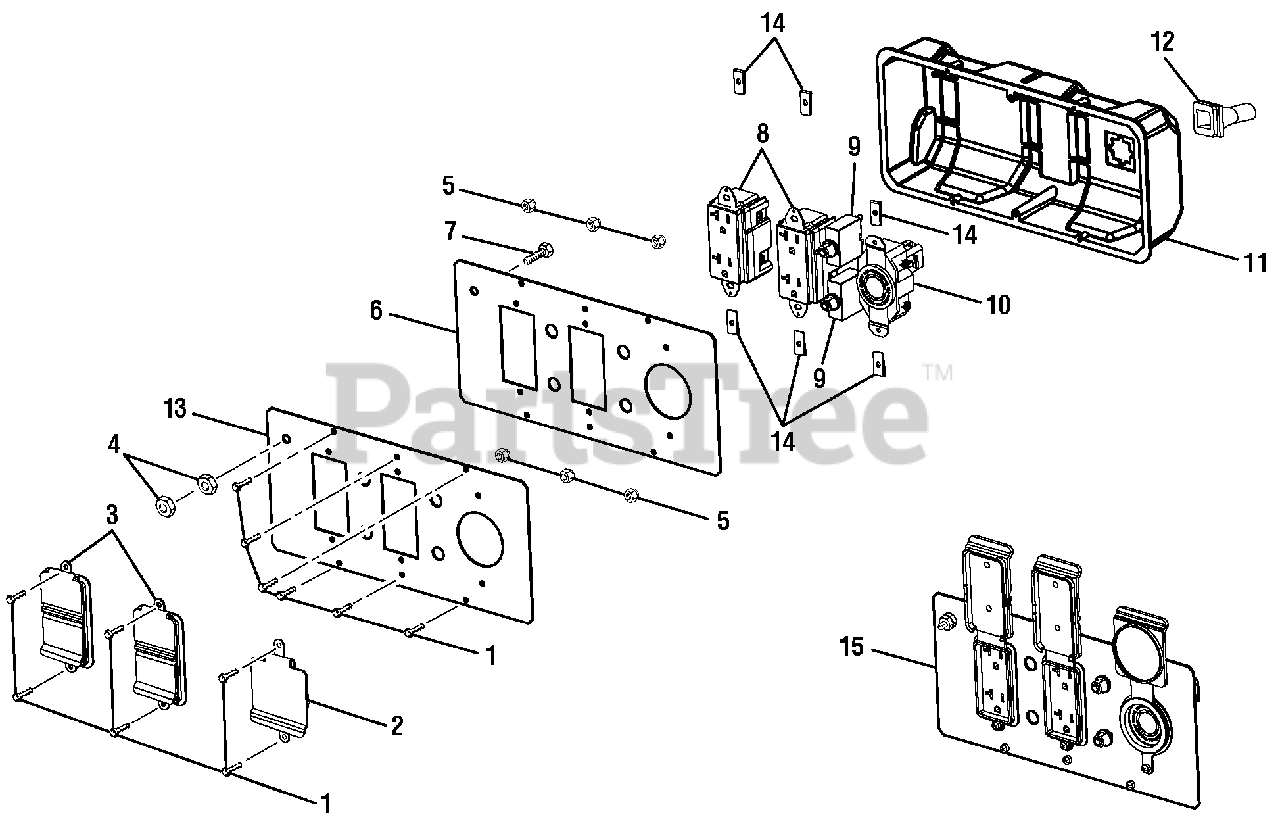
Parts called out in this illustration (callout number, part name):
1	Screw (6-20 x 3/8 in.)
2	Outlet Cover (240 V)
3	Outlet Cover (120 V)
4	Hex Nut (1/4-20)
5	Nut (M6-32)
6	Cover Plate
7	Screw (1/4-20 x 5/8 in., Hex Hd.)
8	Duplex Receptacle (120 V)
9	Circuit Breaker (20 A, 125 V)
10	Twist Lock Receptacle (120/240 V, 20 A)
11	Rear Control Panel
12	Rubber Boot
13	Control Panel Label
14	Speed Nut
15	Front Panel Assembly
